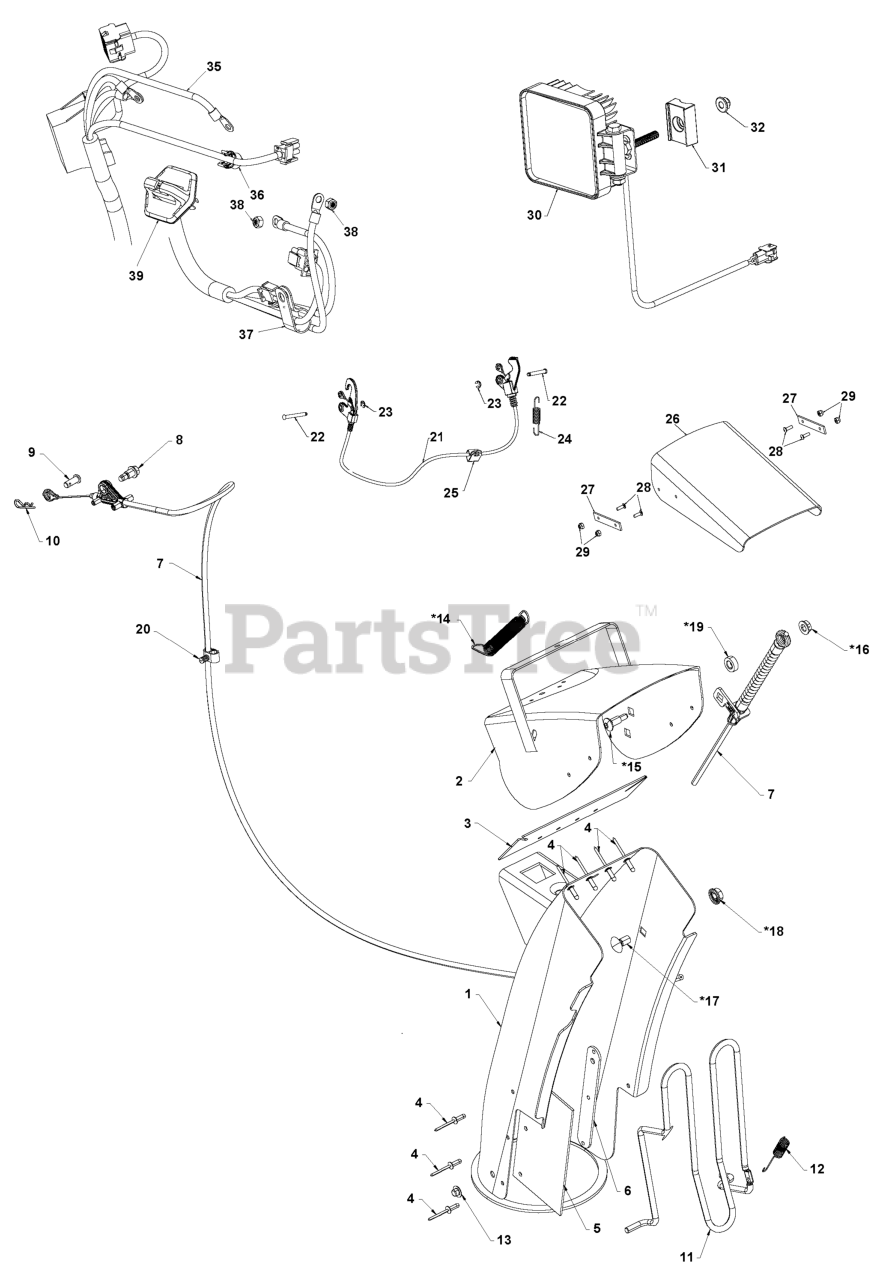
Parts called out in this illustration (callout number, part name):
1	CHUTE.WELDMENT.SNOW.ORANGE
2	ASM.CHUTE/DEFLECTOR.668
3	SEAL.DEFLECTOR
4	RIVET BLIND
5	SHIELD.SNOW.CHUTE
8	BOLT SHOULDER_1/4-20_TRILOB
9	PIN CLEVIS .25 X ..4375
10	HAIRPIN.SOFT.ZINC.059X1.125
11	GUARD ROD CHUTE GUARD SHORT CL
12	SPRING.CHUTE.GUARD
13	NUT
20	CLIP.ROUTING DUAL
21	CABLE INTERLOCK CONTROL ACETAL
22	PIN.GROOVED
25	CLIP.CABLE.BLK
26	SHIELD.DEFLECTOR.BLACK.SNOW
27	STRAP.DEFLECTOR.SHEILD
28	SCREW.MACHINE.8-32 X 1/2-BLK
29	NUT.HEX.NYLOCK
30	LED LIGHTS
31	MOUNTING BRACKET LIGHT MOUNTIN
32	NUT HEXAGON FLANGE 5/16-18 ST
35	HARNESS
36	CLIP CONVOLUTED TUBE, 1/4 BLAC
37	CLIP.CABLE.BLK
38	NUT LOCK NUT M6 NYLOC INSERT H
39	Lifts
